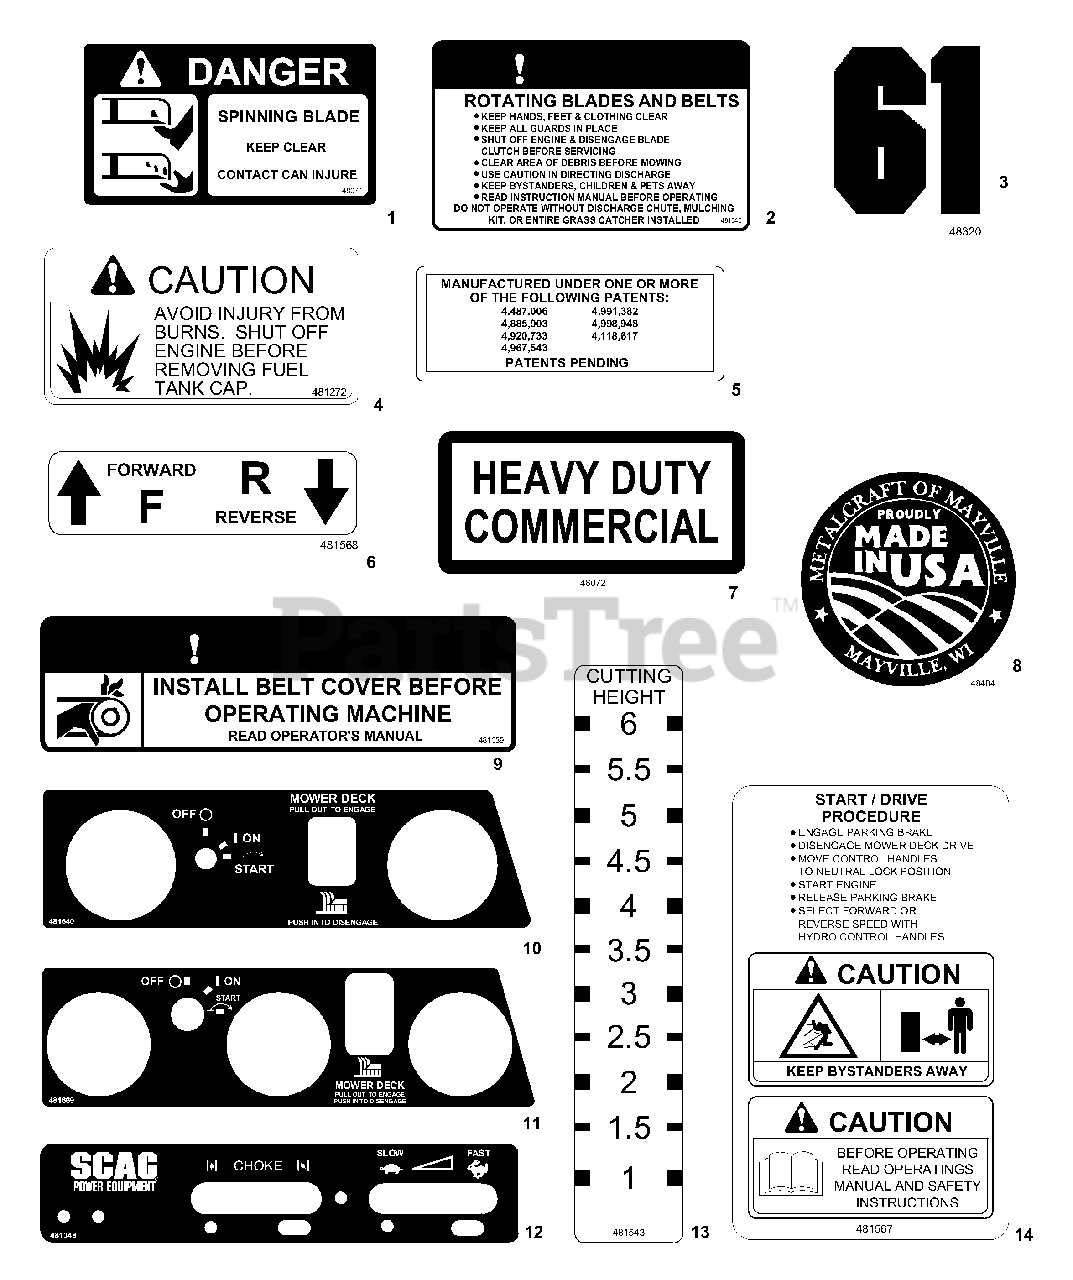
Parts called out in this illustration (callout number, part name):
1	Decal, Danger-Spinning Blades
2	Decal, Warning-Rotating Blades
3	Decal, 52
4	Decal, Fuel Tank
5	Decal, Patents
6	Decal, Traction Control
7	Decal, Heavy Duty Commercial
8	Decal, Metal Craft-Made In USA
9	Decal, Belt Cover
10	Decal, Instrument Panel-Upper
11	Decal, Instrument Panel-Upper (Kawasaki)
12	Decal, instrument Panel-Lower
13	Decal, Cutting Height
14	Decal, Start/Drive Procedure
